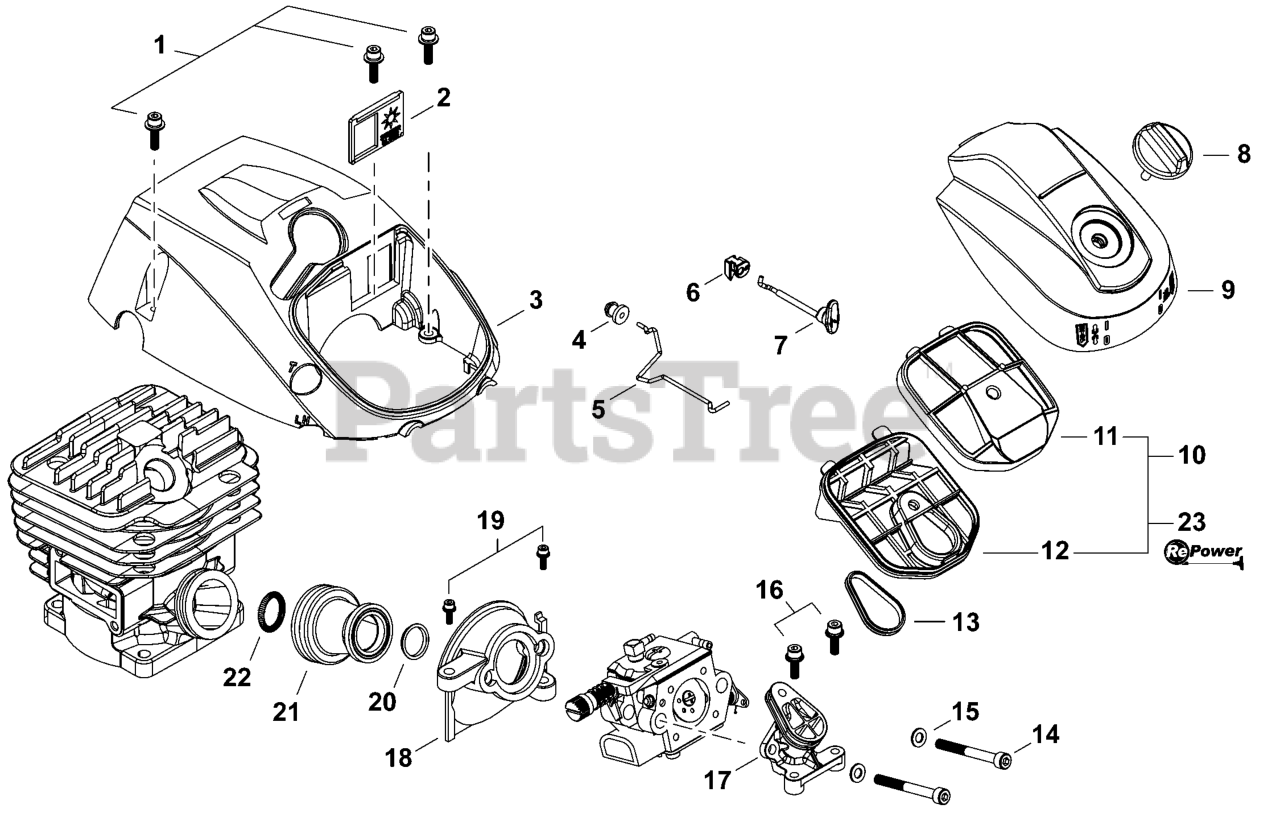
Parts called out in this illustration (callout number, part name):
1	BOLT M4x16
2	PLATE, SHUTTER
3	COVER, ENGINE
4	GROMMET
5	ROD, THROTTLE
6	GROMMET, CHOKE
7	ROD, CHOKE
8	THUMBSCREW
9	COVER, AIR FILTER
10	FILTER ASSY, AIR, FLOCKED
11	FILTER, AIR - FLOCKED UPPER
12	FILTER, AIR - FLOCKED LOWER
14	BOLT M5x48
15	WASHER, FLAT 5.5x10x0.8
16	BOLT M4x16
17	ADAPTOR, AIR FILTER
18	INSULATOR, INTAKE
19	BOLT M4x16
20	COLLAR 16
21	BELLOWS, INTAKE
22	SPRING, TENSION
23	TUNE-UP KIT - REPOWER
